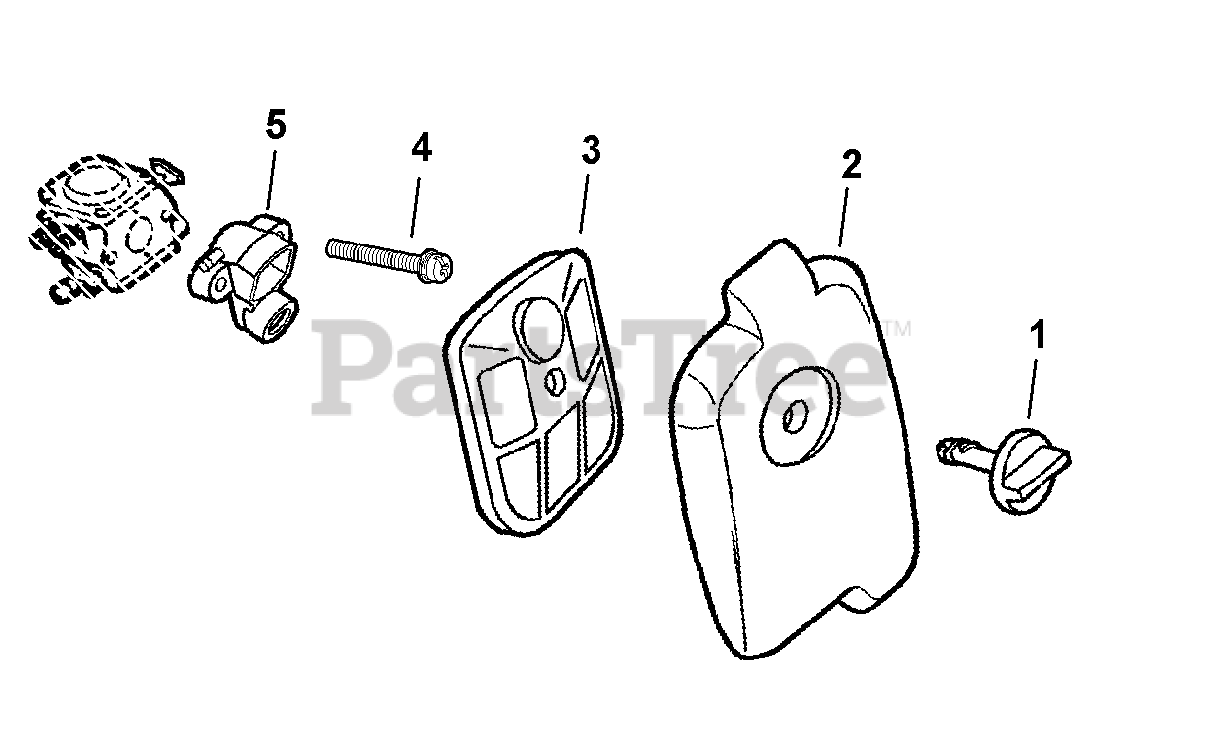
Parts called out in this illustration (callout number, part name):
1	THUMBSCREW
2	COVER, AIR FILTER
3	FILTER, AIR
4	SCREW - 5X50
5	MOUNT, AIR FILTER
